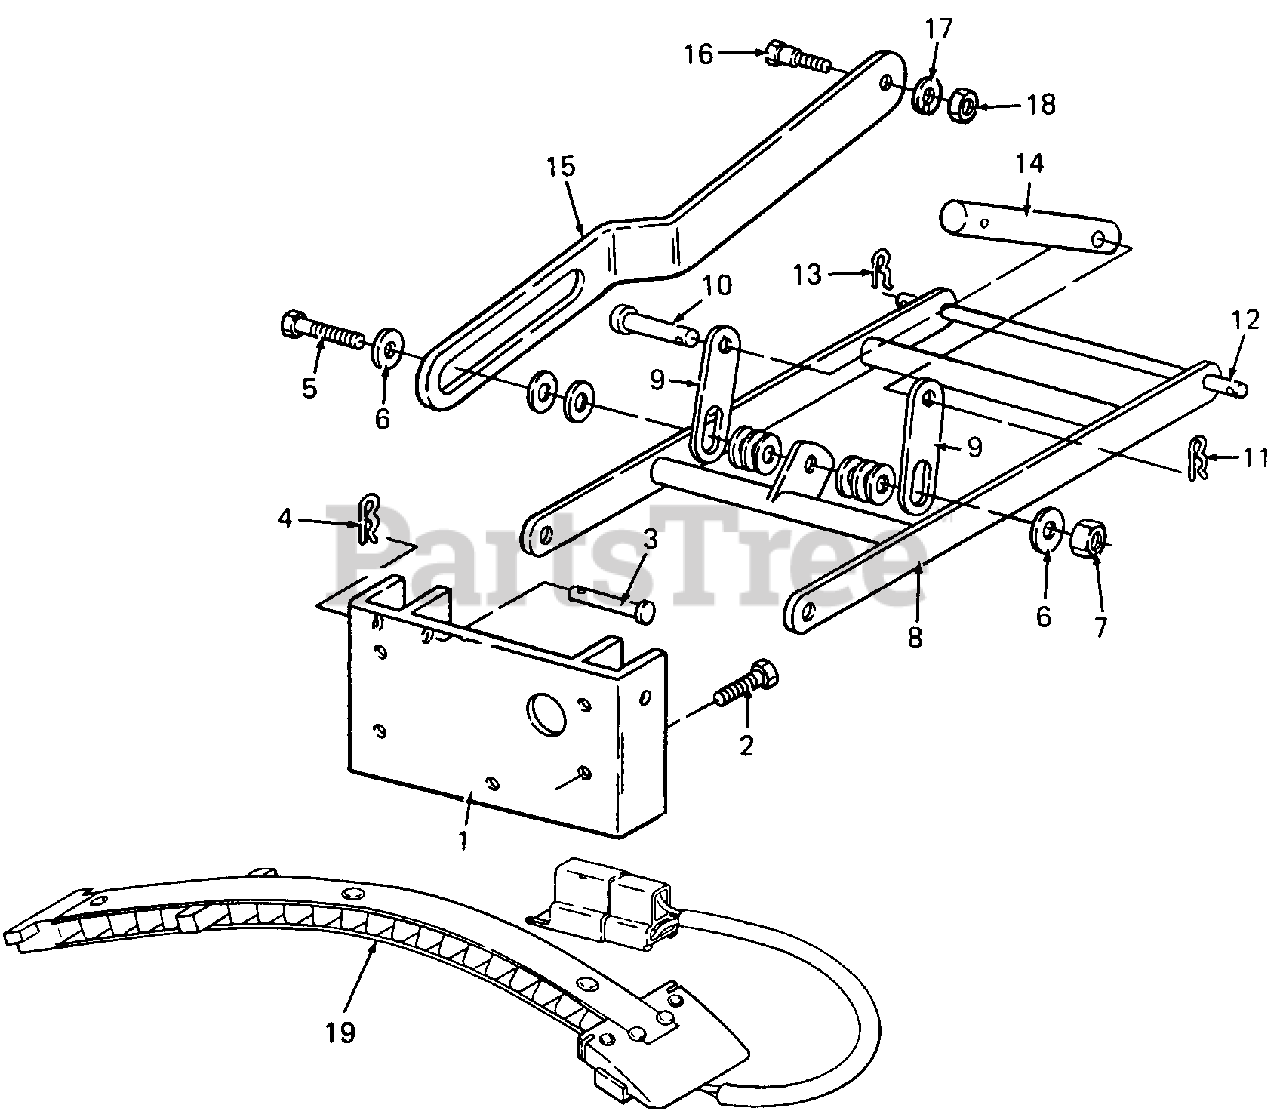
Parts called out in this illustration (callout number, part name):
1	Plate Assy, Mounting
2	Screw, Hex Cap, 3/8-16 X 1.25 Lg GR5
3	Pin, Clevis, 5/8 Dia X 3-1/16 Lg
4	Pin, Internal Cotter, 5/8 Dia
5	Screw, Hex Cap, 1/2-13 X 3.0 Lg GR5
6	Washer, Flat, .531 X 1.25 X .100 Thk
7	Nut, Hex Center Lock, 1/2-13
8	Bar Assy, Hitch
10	Pin, Clevis, 1/2 Dia X 2.17 Lg
11	Pin, Internal Cotter, 1/2 Dia
12	Rod, Hitch
13	Pin, Hitch Clip
14	Shaft, Hitch
15	Link, Stabilizer
16	Bolt, Shoulder
17	Washer, Flat, 5/16
18	Nut, Hex, 5/16-18
19	Switch Assy, NC Beam Seat
